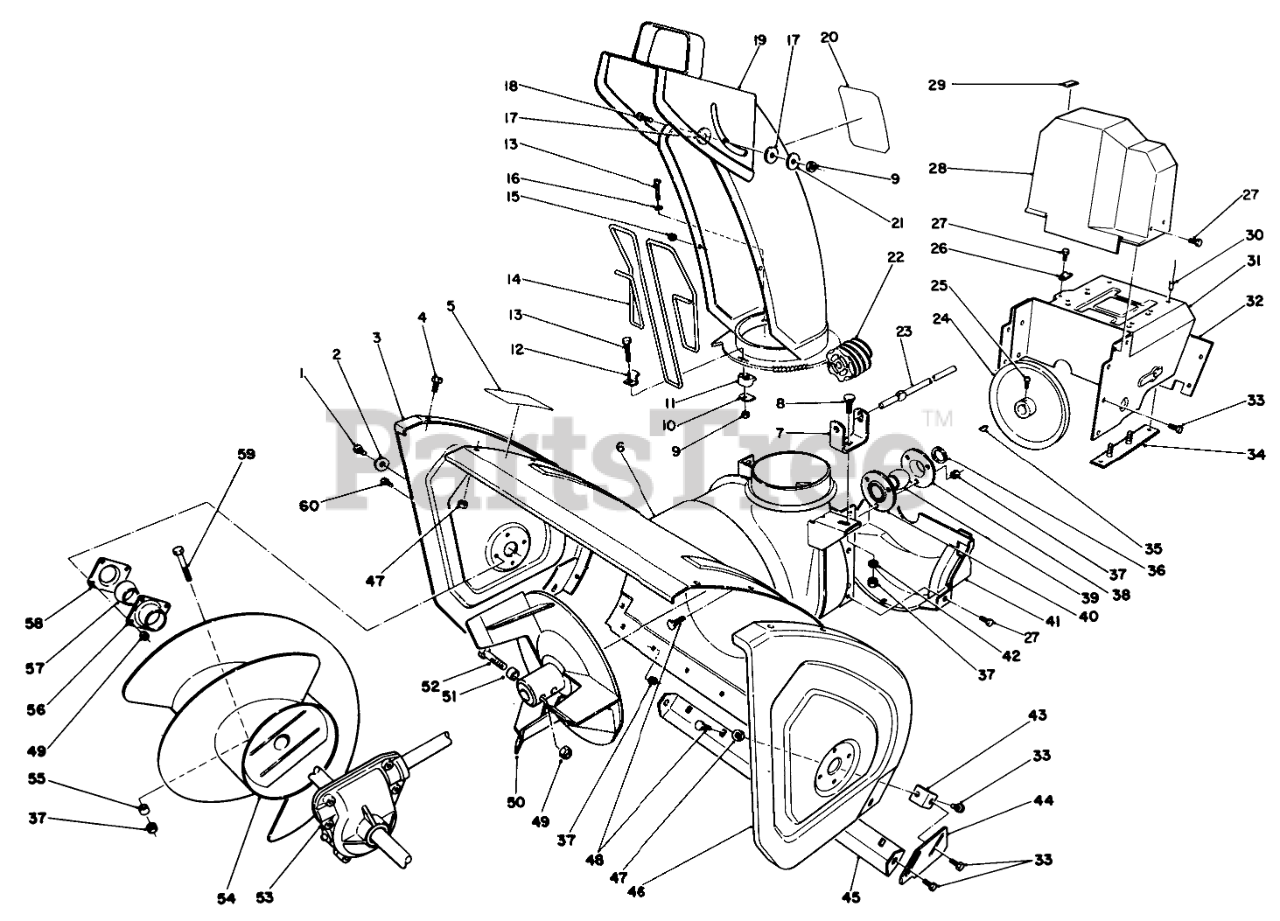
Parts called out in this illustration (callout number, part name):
1	SCREW-HH
2	WASHER
3	PLATE-SIDE, RH
4	SCREW-HHF
5	DECAL-WARNING, AUGER
6	Housing-24 Inch
7	BRACKET-WORM, CHUTE
8	BOLT-CARR
9	NUT-LOCK, NI
10	PLATE-RETAINER, CHUTE
11	RETAINER-CHUTE
12	CLIP-GUARD, CHUTE
13	SCREW-HSH
14	GUARD-CHUTE
15	NUT-PUSH
16	WASHER-FLAT
17	WASHER-PLASTIC
19	Assembly
20	Decal-Danger
21	WASHER-FLAT
22	GEAR-WORM
23	ROD-CHUTE, LOWER
24	PULLEY-IMPELLER
25	SCREW-SET, SQH
26	RETAINER-CABLE
27	SCREW-HWH
28	COVER-BELT, UPPER
29	COVER-CABLE
30	RIVET-POP
31	Frame-Engine
32	Cover-Frame, Engine
33	SCREW-HHF
34	LH FRAME PLATE ASM
35	KEY-WOODRUFF
36	WASHER-THRUST
37	NUT-LOCK, NI
38	Flange-Bearing (Rear)
39	BEARING-BALL
40	Flange-Bearing (Front)
41	Cover-Belt (Lower)
42	WASHER-PLAIN
43	Bracket-Skid
44	Plate-Skid LH
45	Blade-Scraper
46	Plate-Side LH
47	NUT-LOCK, NI
48	SCREW-CARR
49	NUT-LOCK, NI
50	Impeller
51	SPACER
52	SCREW-HHF
53	Auger Gearbox ASM
54	Auger-RH
55	SPACER-HUB, AUGER
56	BEARING-FLANGE, FRONT
57	BEARING
58	BEARING-FLANGE, REAR
59	Auger Bolt
60	SCREW-HH
